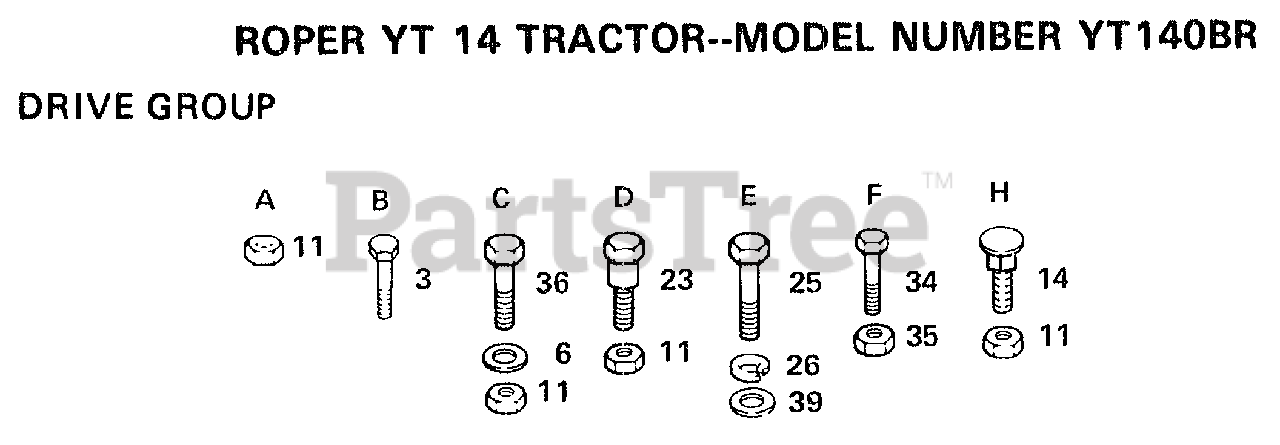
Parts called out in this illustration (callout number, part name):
3	SCREW
6	WASHER
14	BOLT
23	"BOLT, SHOULDER LT"
26	LOCKWASHER
34	BOLT
36	BOLT
